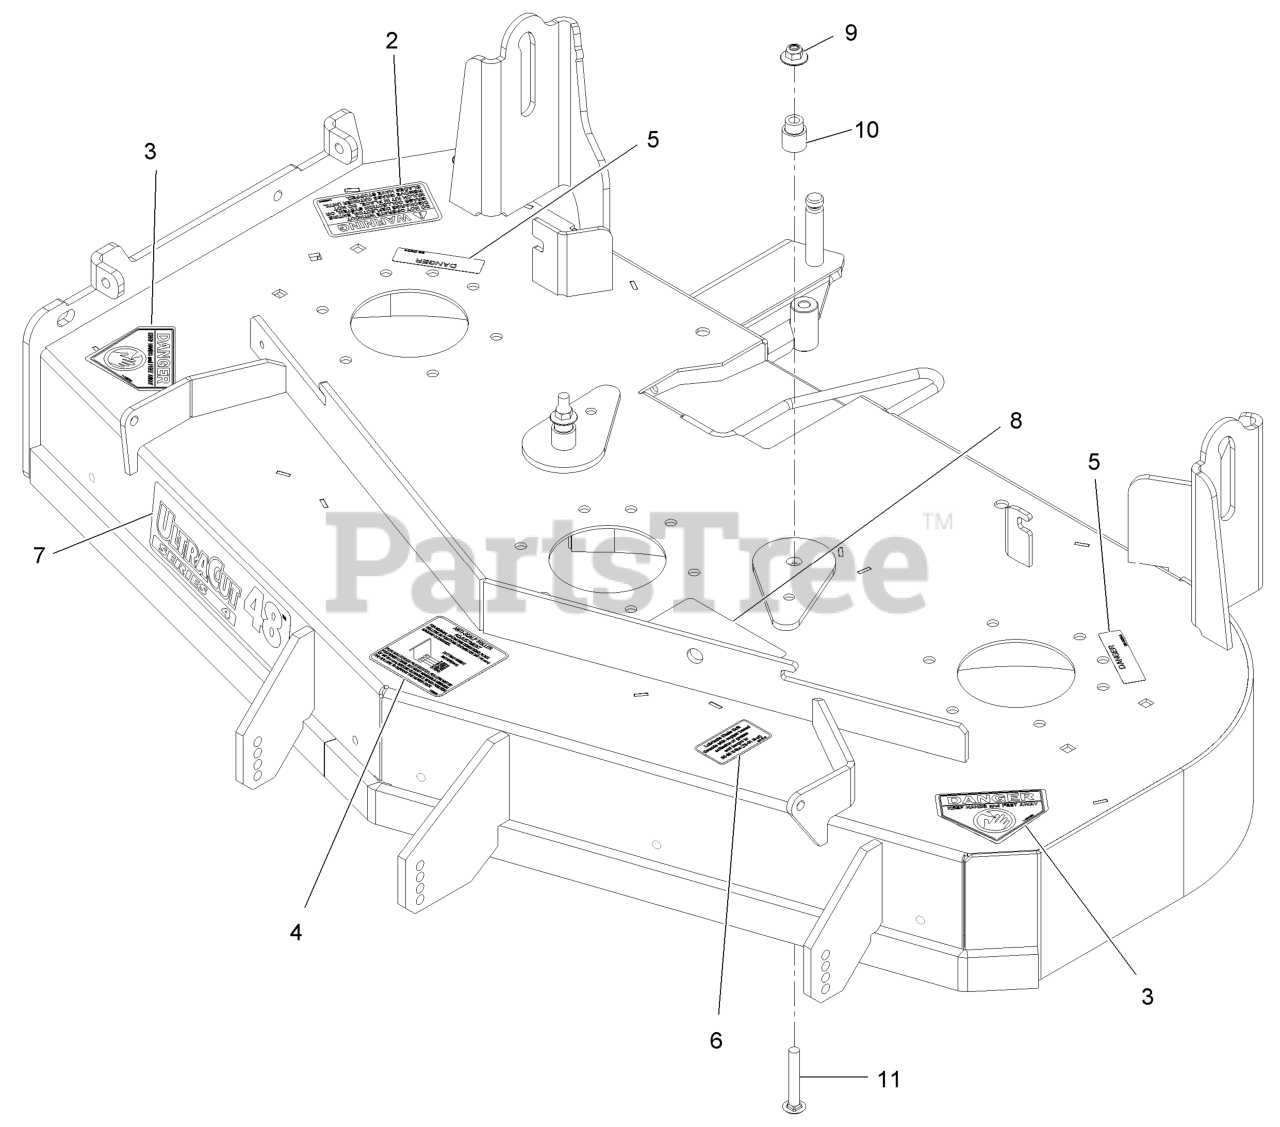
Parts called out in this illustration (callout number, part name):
2	DECAL-WARNING, DISCHARGE
3	DECAL-DANGER
4	DECAL,ANTISCALP
5	DECAL-COVER, MISSING
6	DECAL,BOLT TORQUE
7	DECAL,ULTRACUT 48 SERIES
8	DECAL-BELT ROUTING
9	Nut-Nyloc 3/8-16 Flg
10	BUSHING-IDLER
11	SCREW-CARR
